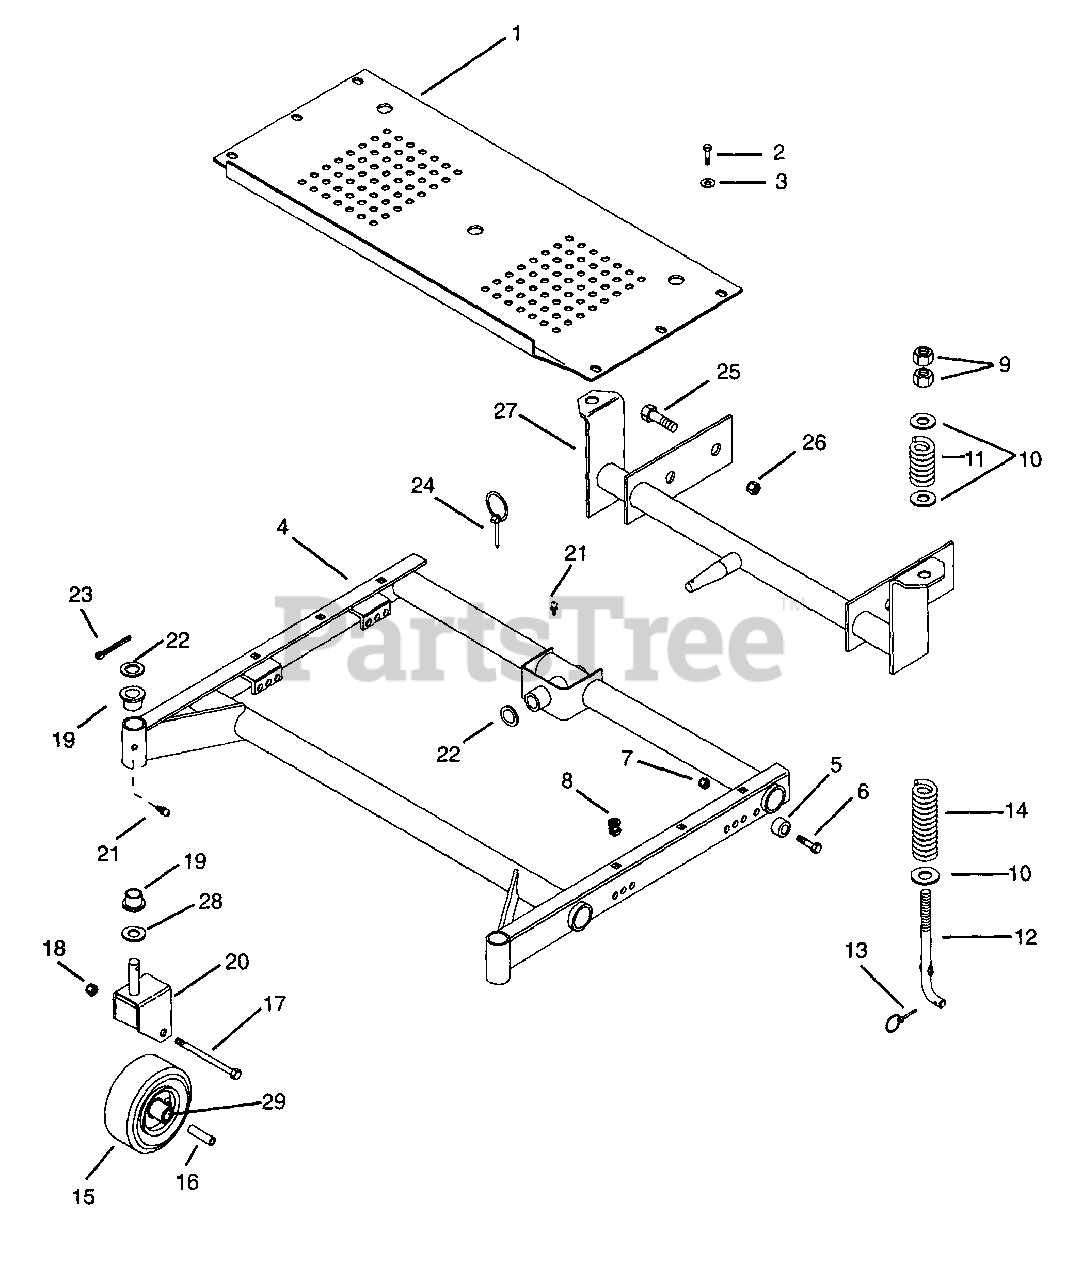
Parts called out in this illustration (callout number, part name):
1	Footboard
2	Screw-Machine .25-20
3	Washer-Flat-Steel .281 x .625 x .065
4	Weldment, Mower Frame 40" 3 Spindle
5	Bushing .391 x .626 x .670
6	Bolt-Hex .38-16 x 1.50 Grade 5
7	Nut-Locking-Nylon .375-16 Grade 2
8	Clip, U-Type
9	Nut .50-13
10	Washer-Flat-Steel .531 x 1.062 x .095
11	Spring-Compression .125 x .78 x 1.00
12	Rod, Height Adjuster
13	Pin-Klik 1.000 x .188 x 1.25
14	Spring Compression .095 x .75 x 6.25
15	Wheel, Gauge 11 x 4-4
16	Bushing, Caster Fork
17	Bolt-Hex .50-13 x 6.50
18	Nut-Locking-Nylon .50-13 Grade 5
19	Bushing-Flange 1.020 x 1.385 x .75 x 1.75
20	Weldment, Caster Fork
21	Fitting-Lube .25-28 x .256
22	Washer-Hardened-Thrust 1.002 x 1.552 x .030
23	Pin-Cotter .12 x 1.25
24	Pin-Klik .25 x 1.75
25	Bolt-Hex .62-11 x 1.50
26	Nut, Locking 5/8-11
27	Weldment, Mower Frame Mounting
28	Washer-Flat-Steel 1.007 x 1.542 x .062
29	Bearing-Ball-Flange .752 x 1.50 x .50
